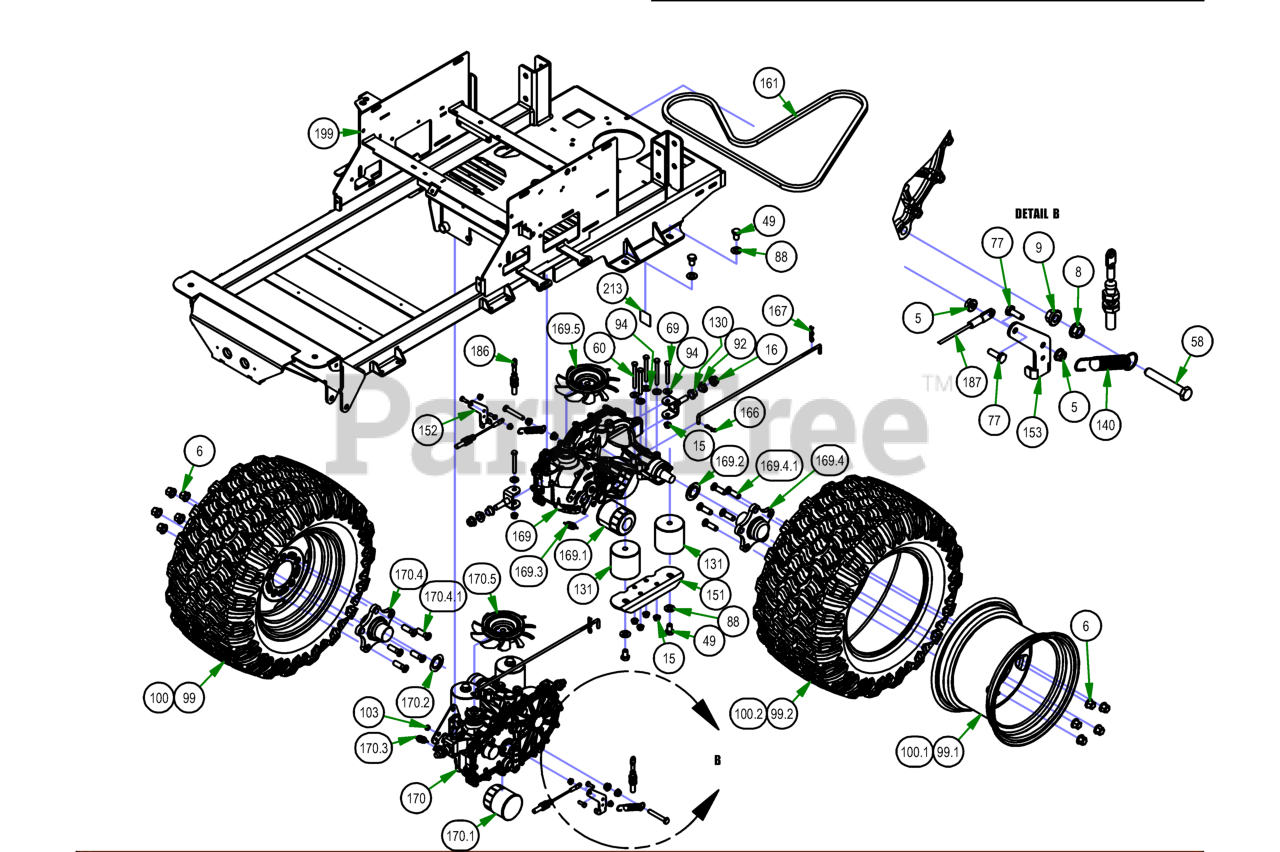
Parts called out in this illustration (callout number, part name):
5	1/4-20 NYL INSERT FLANGE LOCKNUT ZINC
6	Acorn Lug Nut
8	3/8-16 HEX SERRATED FLANGE NUT HARD/ZINC
9	3/8-16 NYLON INSERT FLANGE LOCKNUT (GR.F) ZINC
15	5/16-18 NYLON INSERT FLANGE LOCKNUT ZINC
16	1/2-13 NYLON INSERT FLANGE LOCKNUT ZINC
49	1/2-13 X 3/4 HEX CAP SCREW (GR.5) ZINC
58	3/8-16 X 2-1/2 HEX TAP BOLT (GR.5) ZINC Fully Threaded
60	5/16-18 X 3 HEX CAP SCREW (GR.5) ZINC
69	5/16-18 X 2-1/2 HEX CAP SCREW (GR.5) ZINC
77	1/4-20 X 3/4 HEX CAP SCREW (GR.5) ZINC
88	1/2 SAE FLAT WASHER (1-1/16" OD) GR.8 ZINC YELLOW
92	.525 ID SHOULDER WASHER NYLON
94	5/16 USS FLAT WASHER (7/8 OD) ZINC
99	23x9-12 Reaper Turf Tire & Wheel Assembly
99.1	12x7" Black Wheel
99.2	23x9-12 Reaper Turf Tire Only
100	23x11-12 Reaper Turf Assembly
100.1	12x8.5 Black Wheel
100.2	Tire, 23/11x12 Reaper Turf
103	Drive Arm Transaxle Spacer
116	Neutral Rod
130	.627 ID X .753 OD X .500 LGTH X 1.000 FLG OD X .094 FLG THICK FLANGED BEARING OIL-IMPREG BRNZ
131	Vibration Mount-Green Dot
140	Brake Return Spring
150	Maverick Rear Transaxle Pivot Bracket
151	Rear Suspension Transaxle Mount
152	Brake Arm Ext (Left)
153	Brake Arm Ext (Right)
161	75.8" Pump Belt
167	Neutral Rod Clip
169	2021 LH 3200 Transaxle
169.1	ZT Hydraulic Filter
169.2	2021 ZT/Maverick Transaxle Seat Kit (ZT-2800)
169.3	Gold Transaxle Spring
169.4	5 Bolt Hub Kit
169.4.1	Transaxle Wheel Studs/ Drum Brake Studs
169.5	2021 ZT/Maverick Transaxle Fan/Pulley Kit
170	2021 RH 3200 Transaxle
170.1	ZT Hydraulic Filter
170.2	2021 ZT/Maverick Transaxle Seat Kit (ZT-2800)
170.3	Gold Transaxle Spring
170.4	5 Bolt Hub Kit
170.4.1	Transaxle Wheel Studs/ Drum Brake Studs
170.5	2021 ZT/Maverick Transaxle Fan/Pulley Kit
186	2021 Load Balanced Brake Cable 1
187	2021 Load Balanced Brake Cable 2
199	2021 Maverick Frame - Painted
213	Patent Decal
